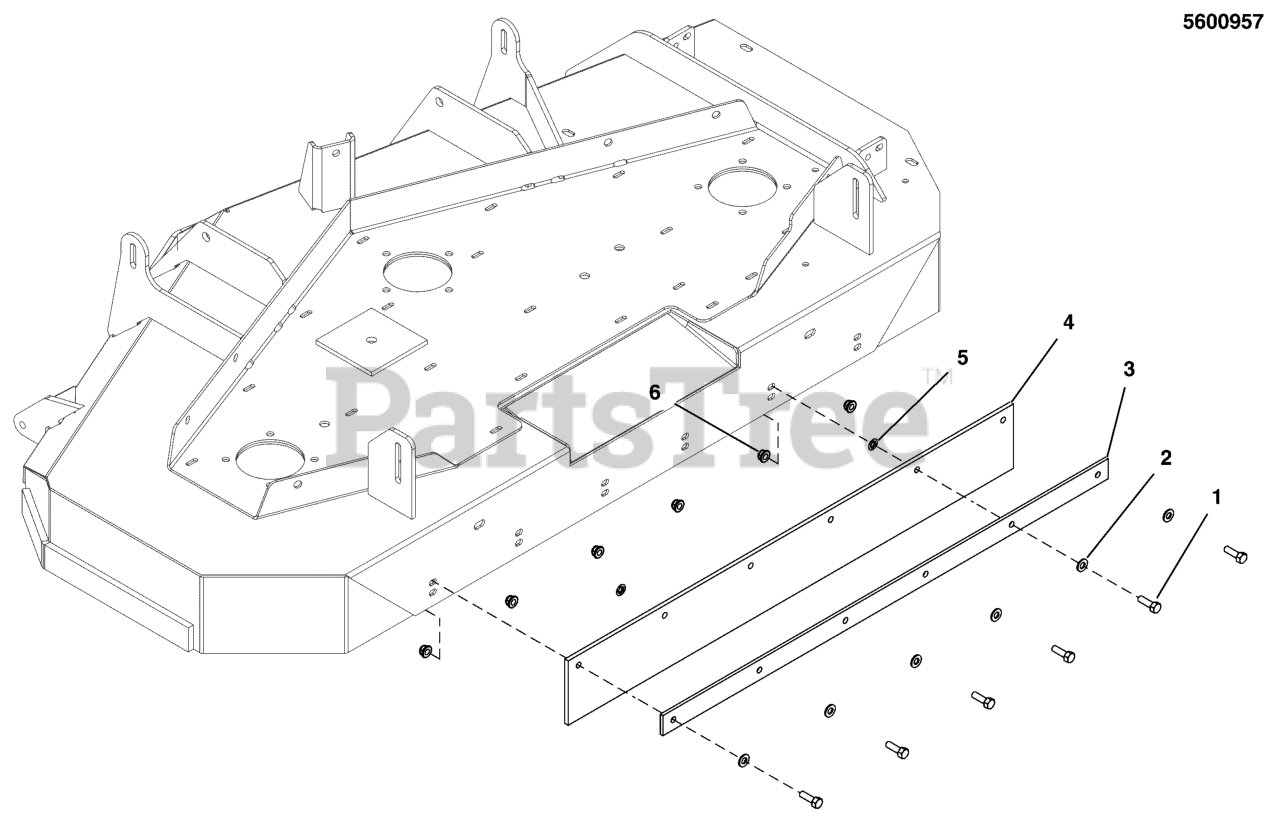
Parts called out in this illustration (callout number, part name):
1	BOLT, 5/16-18 X 1 GD5 CZ
2	WASHER, 5/16" SAE
3	PLATE, SUPPORT - BLK
4	FLAP, STRIPER, 52 DECK
5	5/16 PUSH-ON NUT RETAINER, STL, CZ
6	NUT, 5/16-18 HEX NYLOCK FLANGE
